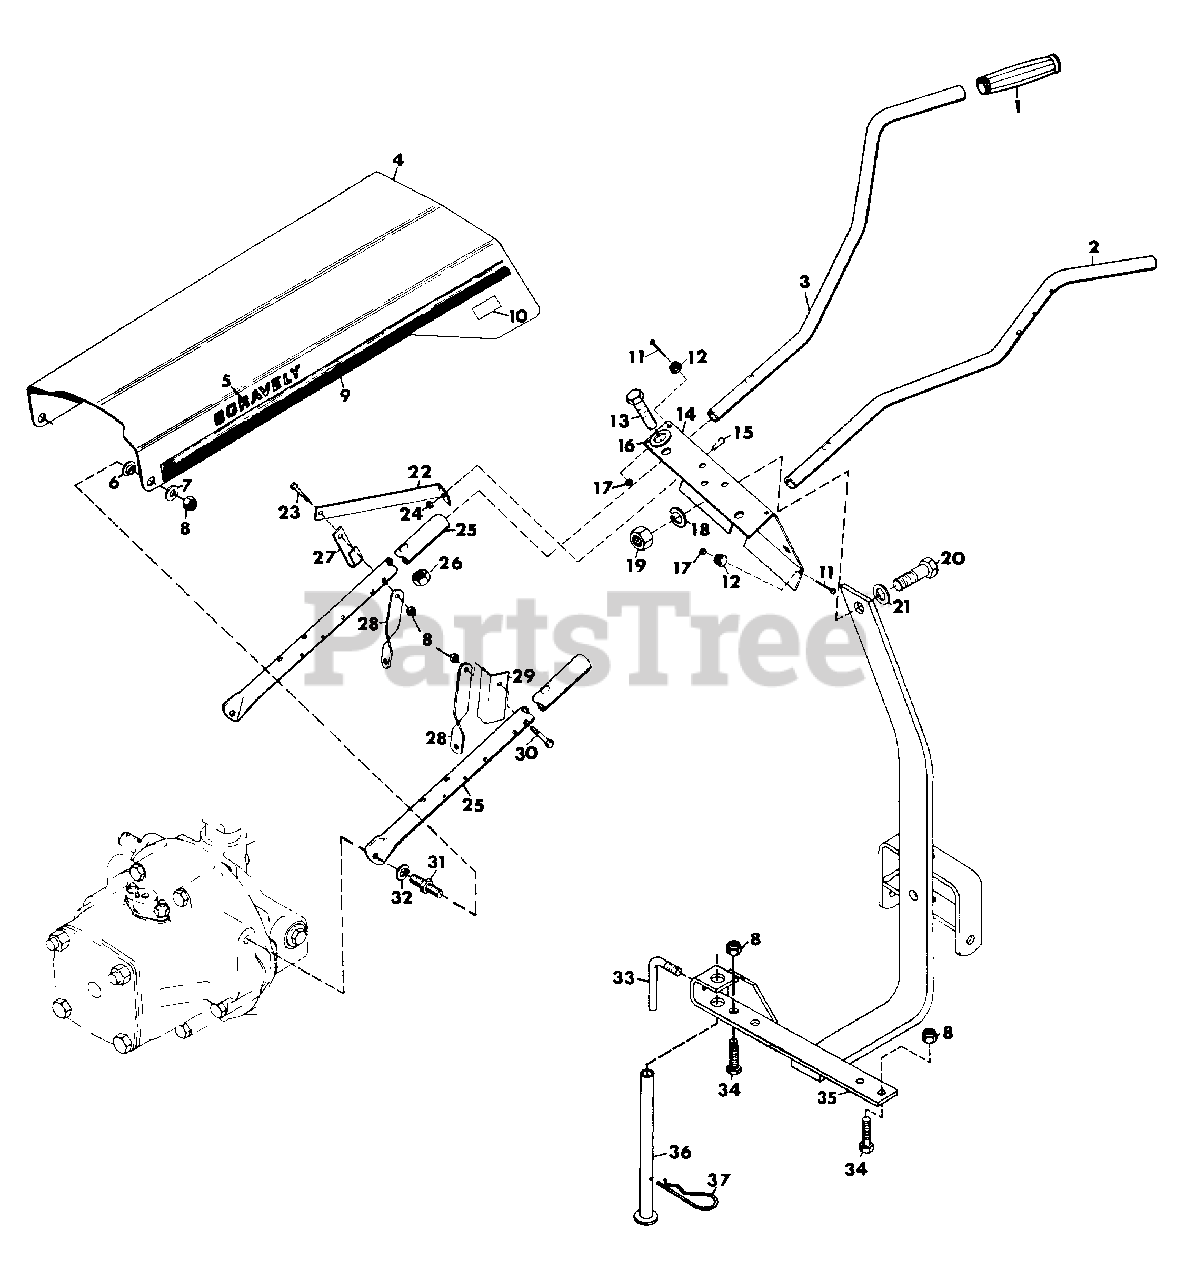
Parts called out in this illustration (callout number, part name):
1	GRIP, HAND
2	BAR, LEFT HANDLE
3	BAR, RIGHT HANDLE
4	HOOD
5	DECAL, GRAVELY LOGO
6	BUSHING
7	WASHER, FLAT .406X.812X.065
8	NUT, LOCK 3/8-16
9	DECAL, SIDE STRIPE
10	DECAL, MODEL 5200
11	SCREW, MACH. 6-32X5/8 PHD
12	BUMPER
13	BOLT, HEX 1/2-20X2
14	PANEL, INSTRUMENT MANUAL START
15	BOLT, HEX 1/4-20X.625
16	WASHER, FLAT .531X1.062X.095
17	NUT, MACH. LOCK 6-32
18	WASHER, LOCK 5/8 SP
19	NUT, HEX 5/8-11
20	BOLT, HEX 5/8-11X1.50
21	WASHER, FLAT .656X1.250X.100
22	BRACE, INSTRUMENT PANEL
23	BOLT, HEX 3/8-16X2.50
24	NUT, LOCK 1/4-20
25	TUBE, SUPPORT
26	NUT, HEX 1/2-20
27	RETAINER, 2-SPEED CONTROL
28	BRACE, HANDLE
29	STOP, ROD
30	BOLT, HEX 3/8-16X2.25
31	STUD, HOOD
32	WASHER, LOCK 3/8 REG.
33	HANDLE, ADJUSTING
34	BOLT, HEX 3/8-16X1.50
35	HITCH, WELDMENT 8 H.P.
36	KICK STAND
37	PIN, HAIR
NS	DECAL, AMERICA
